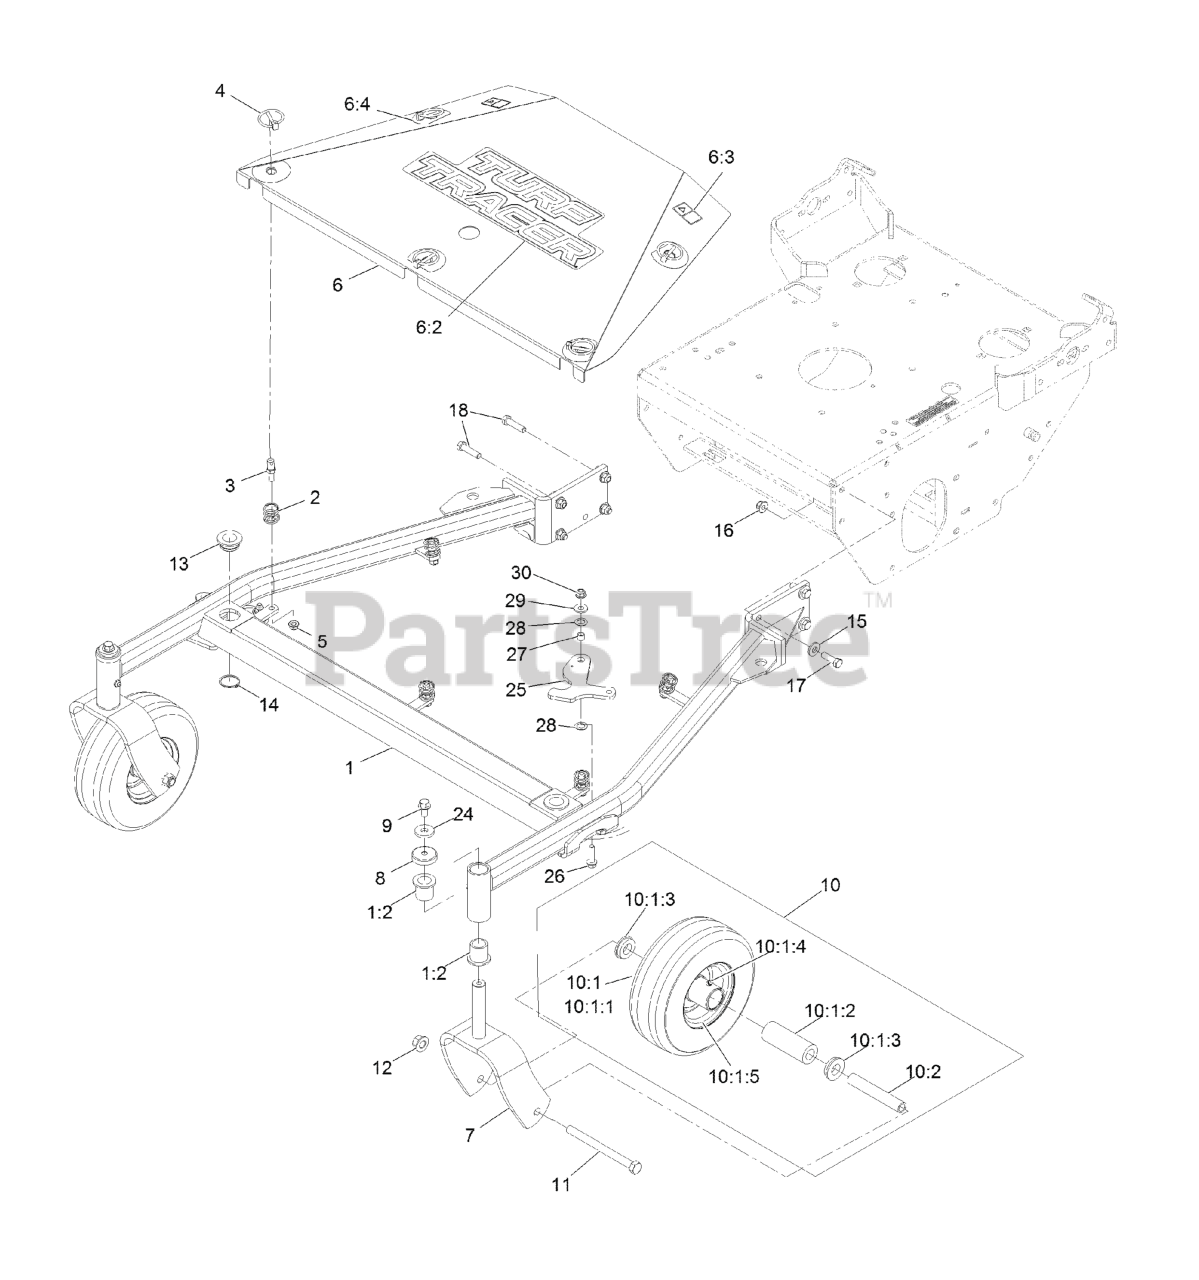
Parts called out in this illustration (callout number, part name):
1	ASM, FRAME W/ BUSHINGS, 5
1:2	BEARING-FLANGED
3	PIN-SPRING
4	PIN-LYNCH
5	NUT-HF, NI
6	ASM, SHIELD W/ DECALS, 52
6:2	DECAL-TURF TRACER
6:3	DECAL-WARNING
6:4	DECAL-SCRATCH COVER
7	FORK, CASTER
8	CAP, DUST
9	SCREW-HHF
10	KIT, SP CASTER WHEEL REPL
10:1	Wheel And Tire ASM
10:1:1	Tire
10:1:2	BEARING
10:1:3	BUSHING
10:1:4	FITTING-GREASE
10:1:5	Wheel
11	SCREW-HH
12	Nut-Lock 1/2-13
13	BUSHING-DECK
14	RING-RETAINING
15	WASHER-BELLEVILLE
16	NUT-HF, NI
17	SCREW-HH
18	SCREW-HH
25	LATCH, DECK HEIGHT
26	Screw-HHF
27	Spacer-Grommet
28	WASHER-CONICAL
29	WASHER-FLAT
30	NUT-HF, NI
